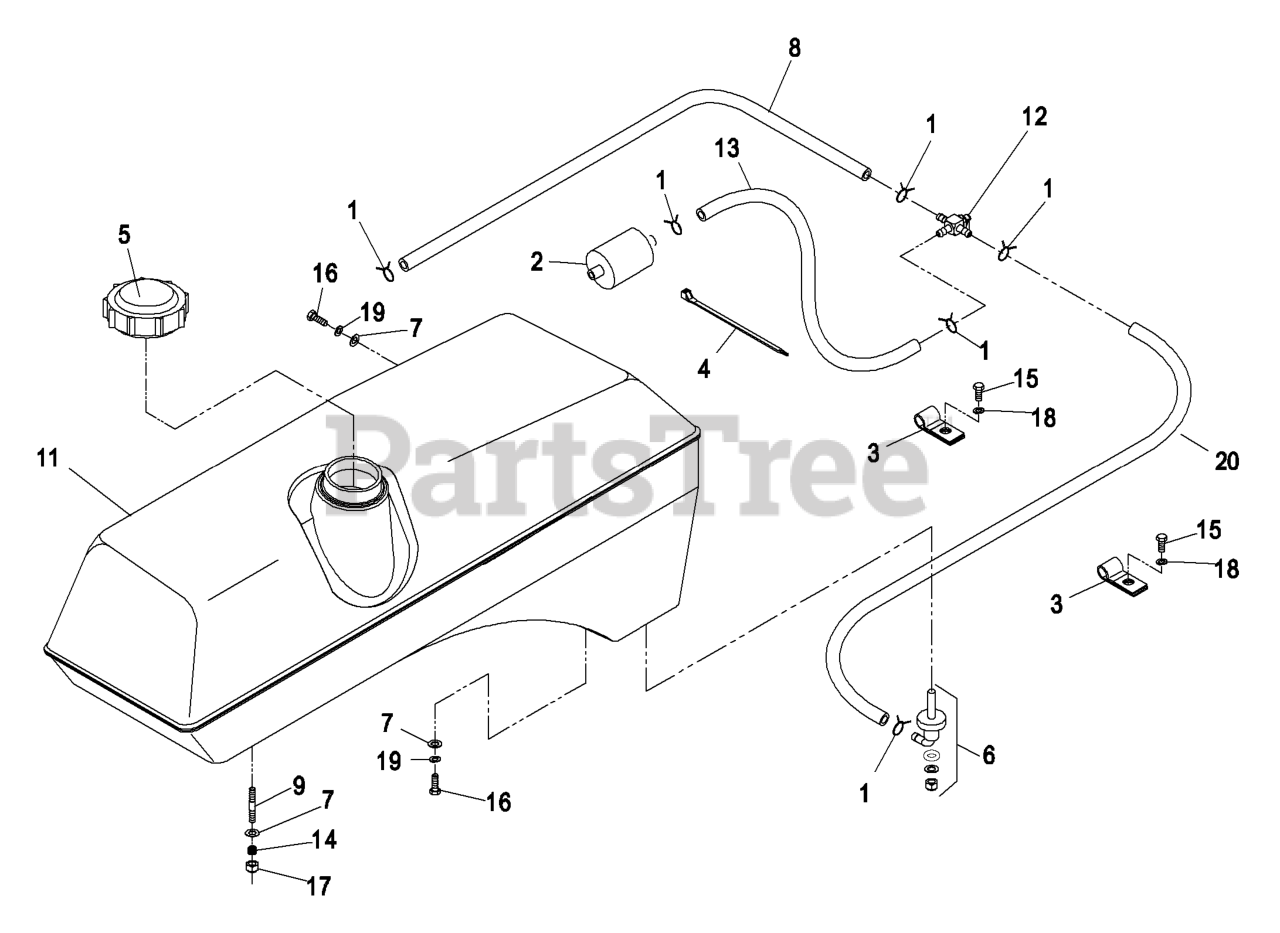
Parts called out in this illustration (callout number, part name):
2	Part No. 2405002 Fuel Filter
3	CLIP-LOOM
4	TIE-PLASTIC
6	FITTING-FUEL, BULKHEAD
7	WASHER-PLAIN
8	HOSE-FUEL
9	STUD
12	VALVE-FUEL
14	SPRING-TANK, FUEL
15	SCREW-HH
16	SCREW-HH
17	NUT-LOCK, NI
18	WASHER-LOCK
19	WASHER-LOCK
20	HOSE-FUEL
